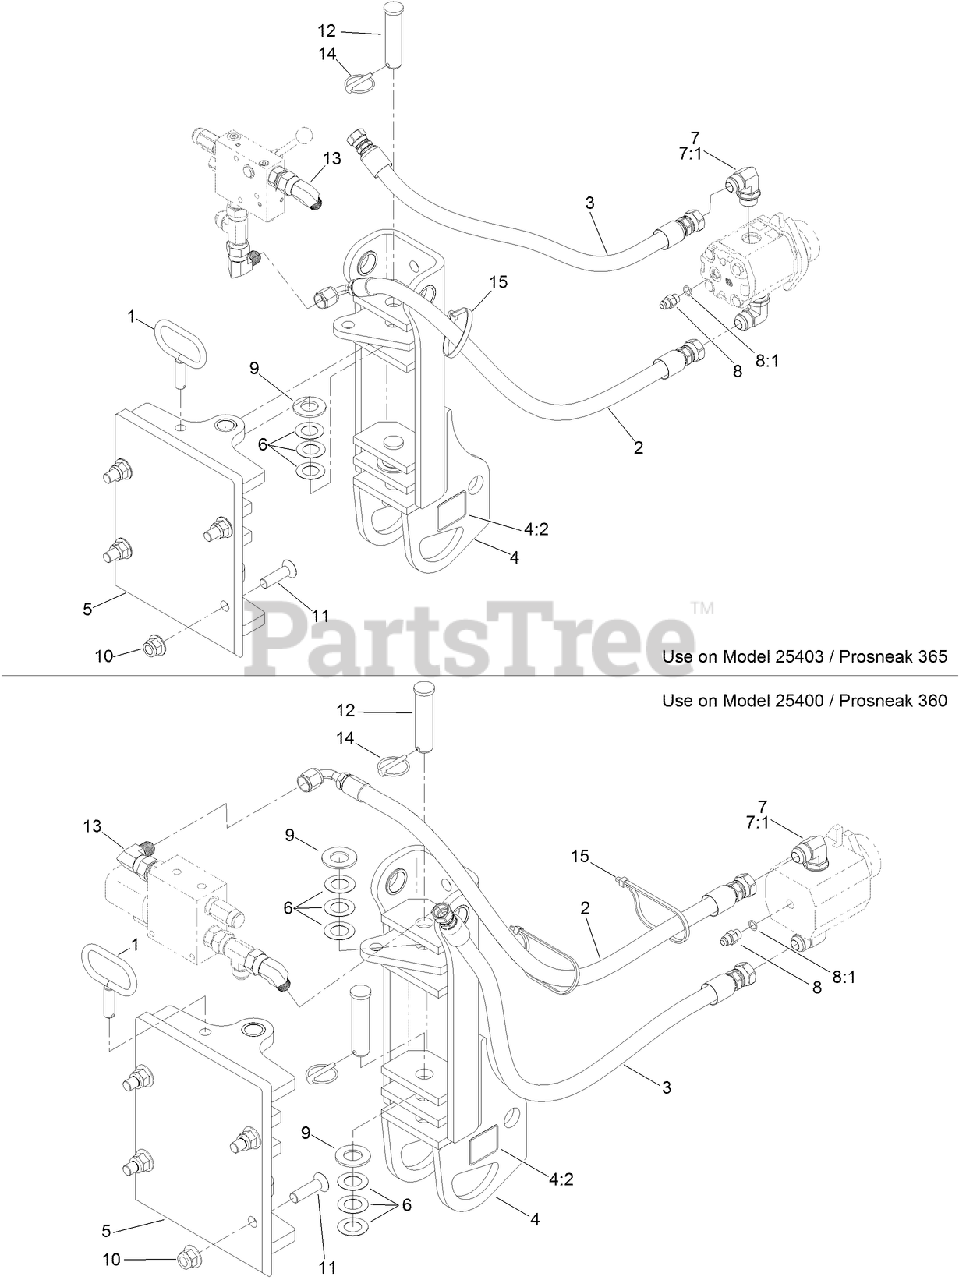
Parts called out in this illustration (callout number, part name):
1	LOCK-SWING
2	HOSE ASM
3	HOSE ASM
4	PIVOT ASM
4:2	DECAL-TIE DOWN
5	SLIDE-QUICK ATTACH
6	WASHER-FLAT
7	FITTING-ELBOW, 90 DEG
7:1	O-RING
8	FITTING-STRAIGHT
8:1	O-RING
9	WASHER-FLAT
10	NUT-HHF
11	SCREW-HSFH
12	PIN-PIVOT
13	FITTING-ELBOW, 90
14	PIN-KLIK
15	TIE-CABLE
